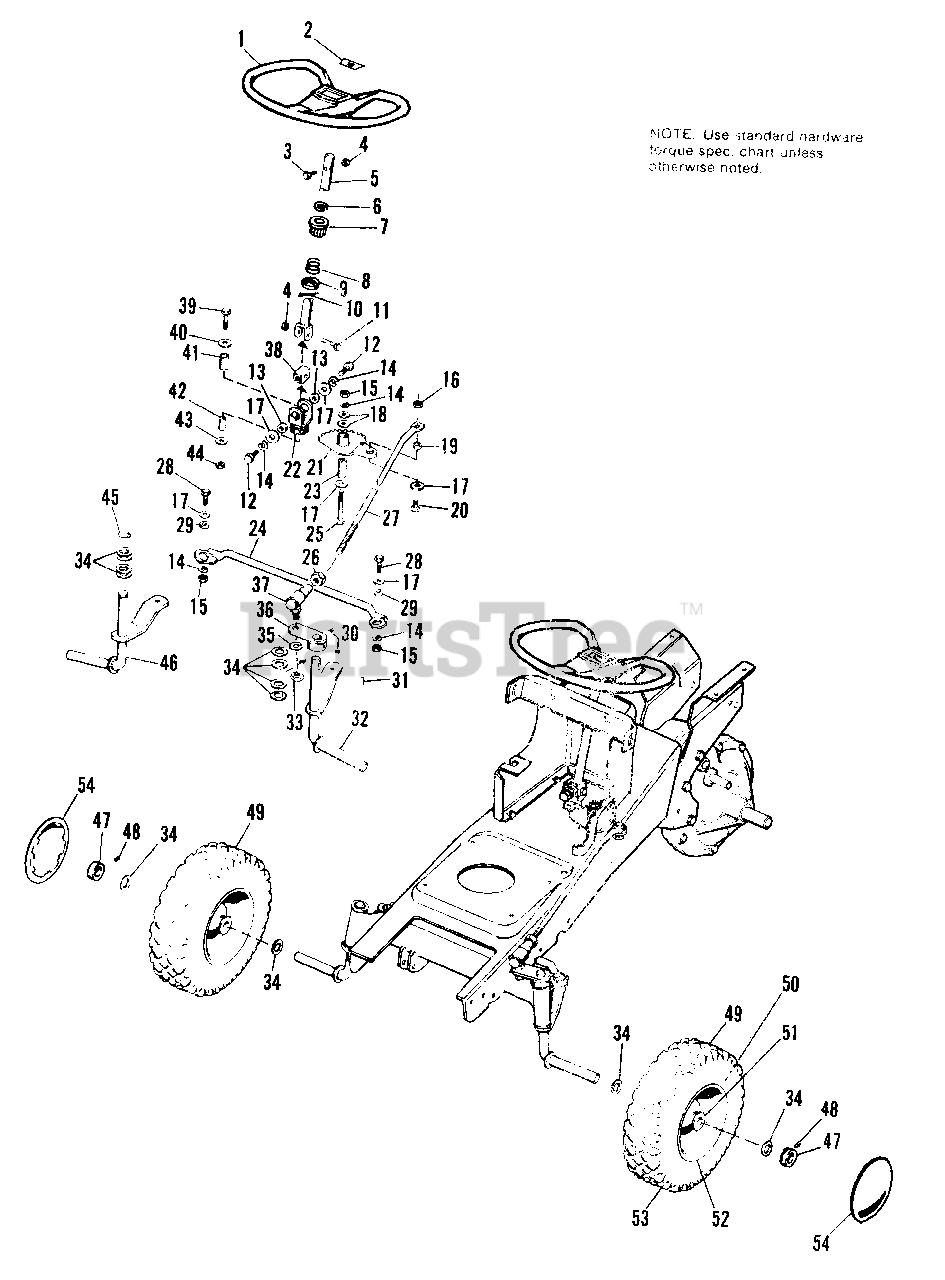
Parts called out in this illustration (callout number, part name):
1	WHEEL ASSY., Steering
3	CAPSCREW, Hex Hd., 5/16-18 x 1-1/4
4	LOCKNUT, Hex, 5/16-18
5	SHAFT ASSY., Steering
6	RING, Retaining
6	RING, Snap (990486, 990542, 990597 & 990598 Only)
9	CUP, Spring
10	PIN, Cotter, 3/16 x 1-1/4
11	CAPSCREW, Hex Hd., 5/16-18 x 1-1/2
12	CAPSCREW, Hex Hd., 3/8-16 x 3/4
14	LOCKWASHER, 3/8
15	NUT, Hex, Full, 3/8-16
16	LOCKNUT, Hex, 3/8-16
17	WASHER, Plain, 3/8
18	WASHER
20	CAPSCREW, Hex Hd., 3/8-16 x 1
21	GEAR ASSY., Steering
22	FORK & PINION ASSY.
24	LINK ASSY., Drag
25	CAPSCREW, Hex Hd., 3/8-16 x 2-1/2
26	LOCKNUT, Hex, Jam, 1/2-20
28	SCREW, Special, 3/8-16 x 1-1/4
30	SETSCREW, 5/16-18 x 1/2
32	SPINDLE ASSY., L.H.
33	NUT, Hex, Full, 1/2-13
35	LOCKWASHER, 1/2
36	LEVER ASSY., Steering
37	JOINT, Ball
38	PIN, Universal Joint
39	CAPSCREW, Hex Hd., 3/8-16 x 1-1/2
43	WASHER, Plain, 5/16
44	LOCKNUT, Hex, Jam, 3/8-16
45	RING, Retaining
46	SPINDLE ASSY., R.H.
47	COLLAR, Set
48	SETSCREW, 5/16-18 x 5/16
49	WHEEL & TIRE ASSY.
51	BEARING (for Service)
54	CAP, Hub, Front
